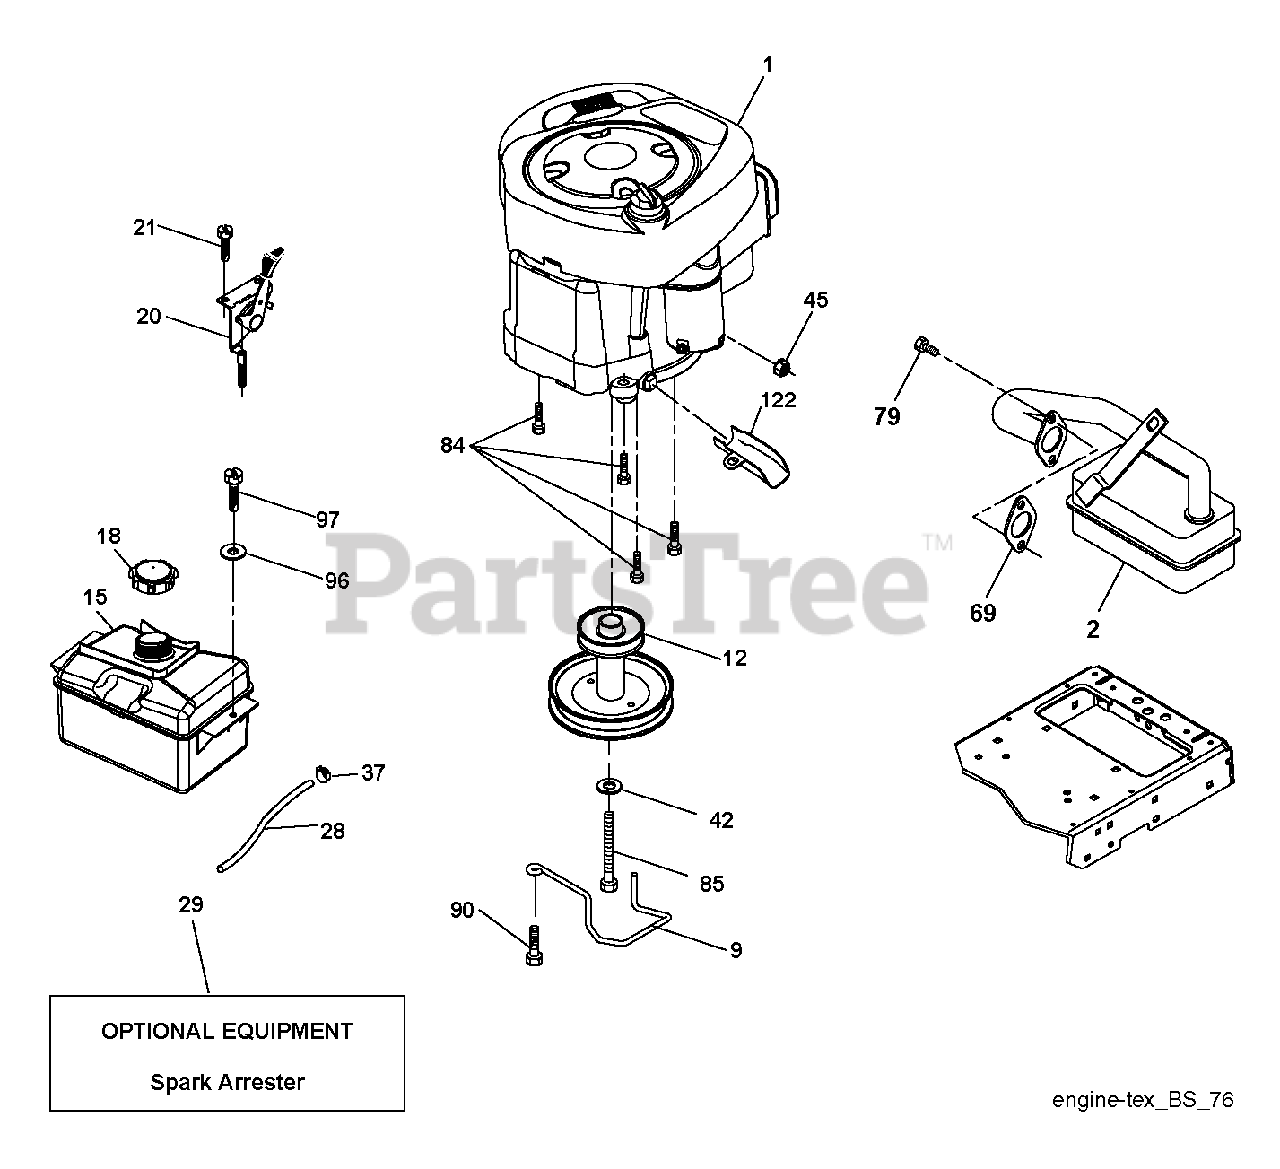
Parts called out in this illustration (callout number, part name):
2	MUFFLER.SINGLE.CYL.KOHL/B&S
9	KEEPER.BELT.ENGINE.4.2
12	PULLY ENGINE
15	RP TANK FUEL FRT 1.5 GAL
18	CAP ASM.FUEL.2.25"FR.
20	CONTROL.TH/CK.C.
21	SCREW.#10 X 0.750.BOS
28	LINE.FUEL.20
29	KIT.SPARK ARRESTOR 794945 B&S
37	HOSE CLAMP
42	LOCKWASHER
45	NUT
69	GASKET.EXHAUST.KOHLER
79	SCREW.SOCKET HD.5/16-1
84	SCREW.3/8-16
85	BOLT HEX 7/16-20X4-1/4"
90	SCREW 3/8-16X1
97	SCREW HEXWSHR 1/4-20X3/4
122	EXTENSION DRAIN OIL
